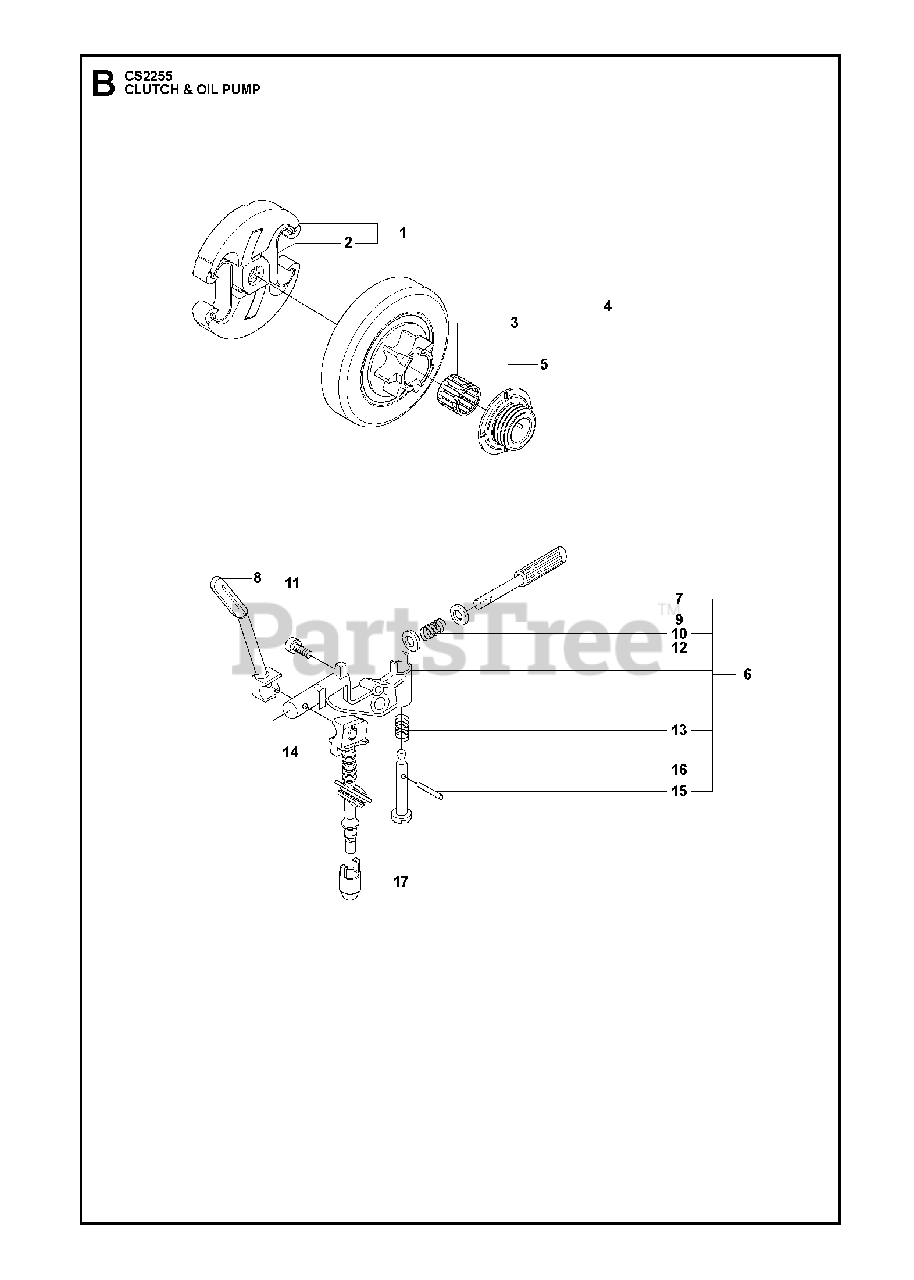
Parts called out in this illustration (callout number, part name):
2	SPRING
3	NEEDLE BEARING
4	CLUTCH DRUM
5	PINION
6	OIL PUMP ASSY
7	PUMP PISTON
9	WASHER
10	SPRING
12	WASHER
13	SPRING
14	RP OIL HOSE
15	PIN
16	SCREW
17	OIL SCREEN
